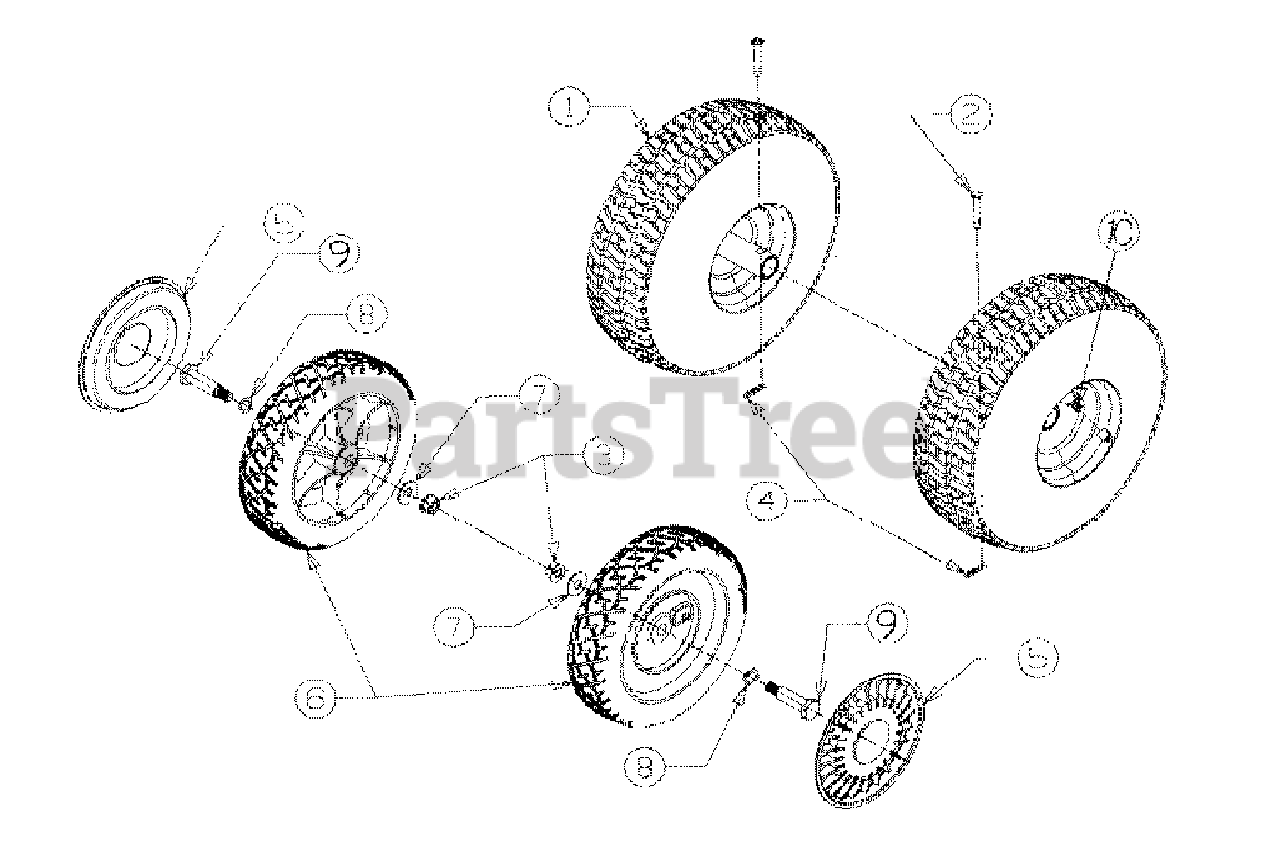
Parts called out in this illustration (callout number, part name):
2	PIN-CLEVIS
3	NUT-HEX FLANGE
4	PIN-COTTER
5	HUB CAP
6	WHEEL
7	WASHER-BELL
8	WASHER-WAVE
9	SCREW-SHOULDER
10	VALVE STEM
